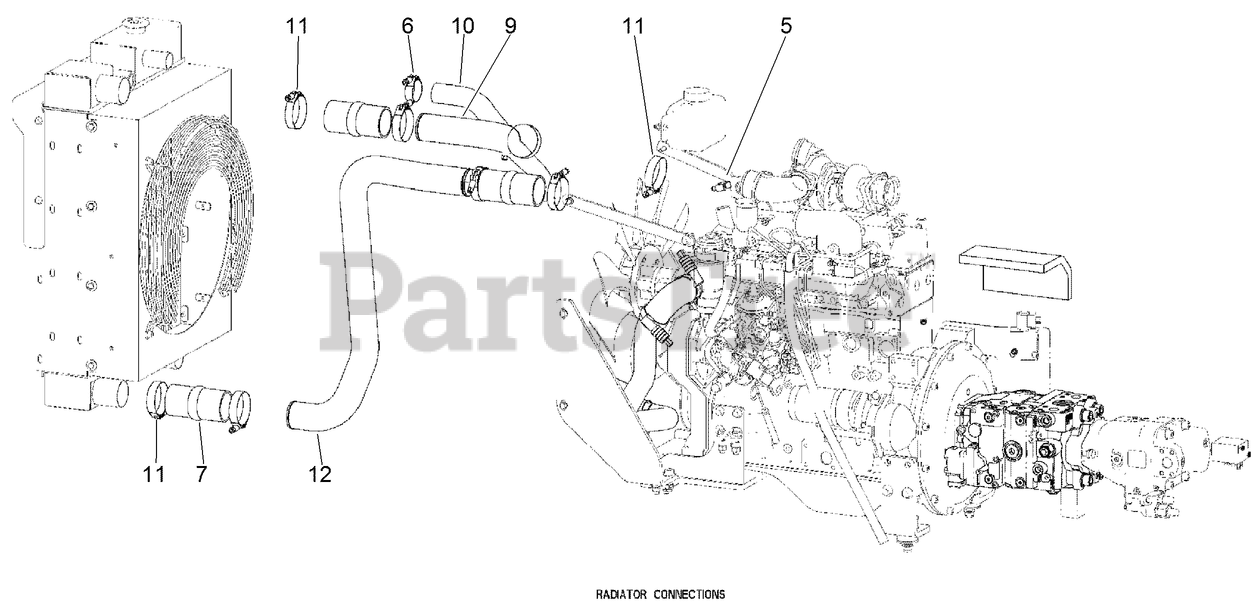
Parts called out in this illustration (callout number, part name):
5	CLAMP - Hose Type F # 24
6	CLAMP-HOSE (T-BOLT)
7	CONNECTOR - 2.5 Silicon Charge Air
9	CHARGED AIR - Upper Tube
10	HOSE - Upper Radiator
11	CLAMP - Constant Torque
12	CHARGED AIR - Lower Tube
